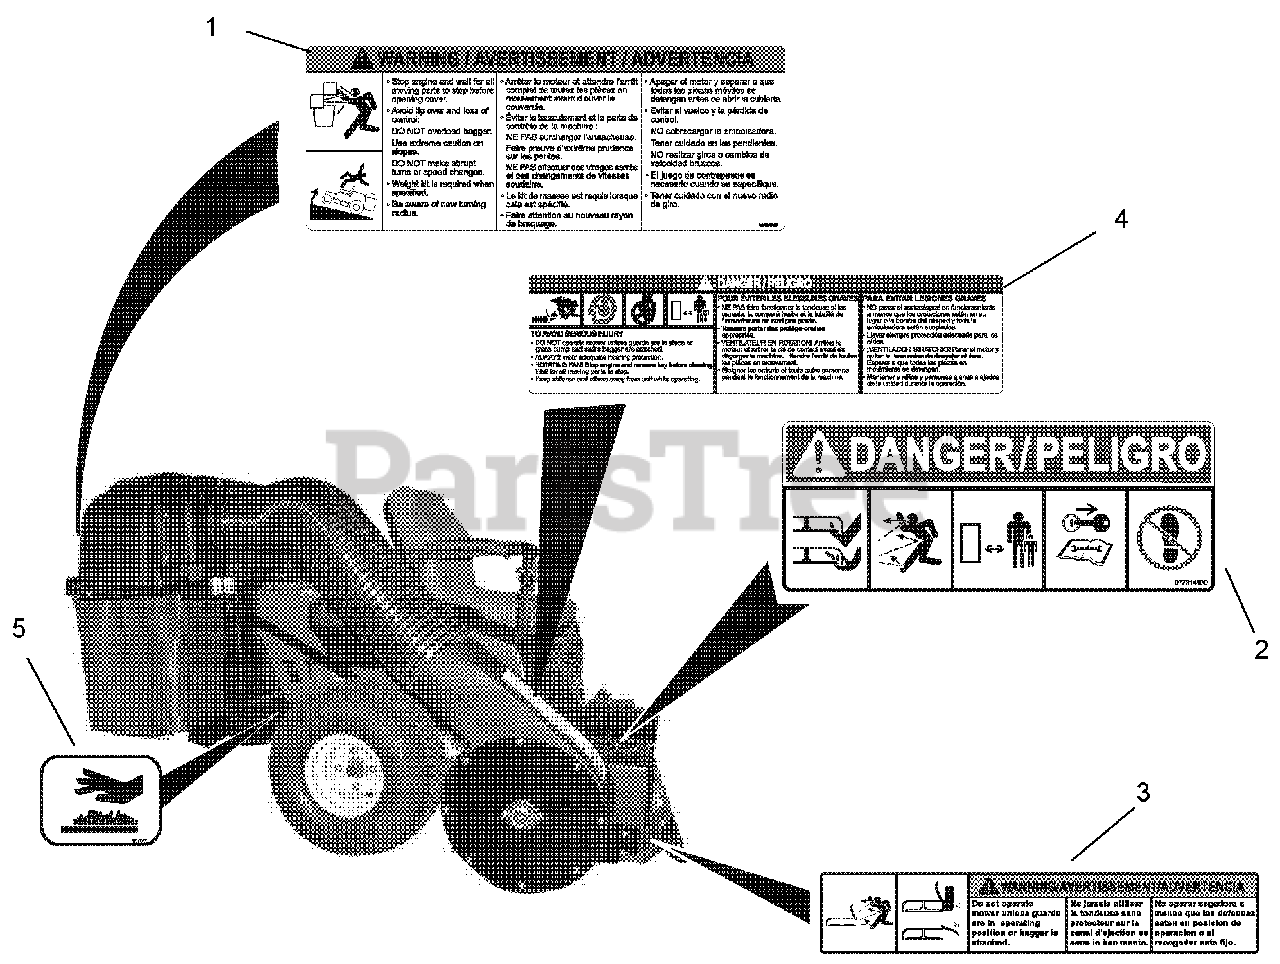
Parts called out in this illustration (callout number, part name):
1	DECAL, BAGGER COVER
2	DECAL, MOWER PAN DANGER
3	DECAL, WARNING
4	DECAL-CAUTION, GRASS PUMP
5	DECAL, HOT SURFACE
